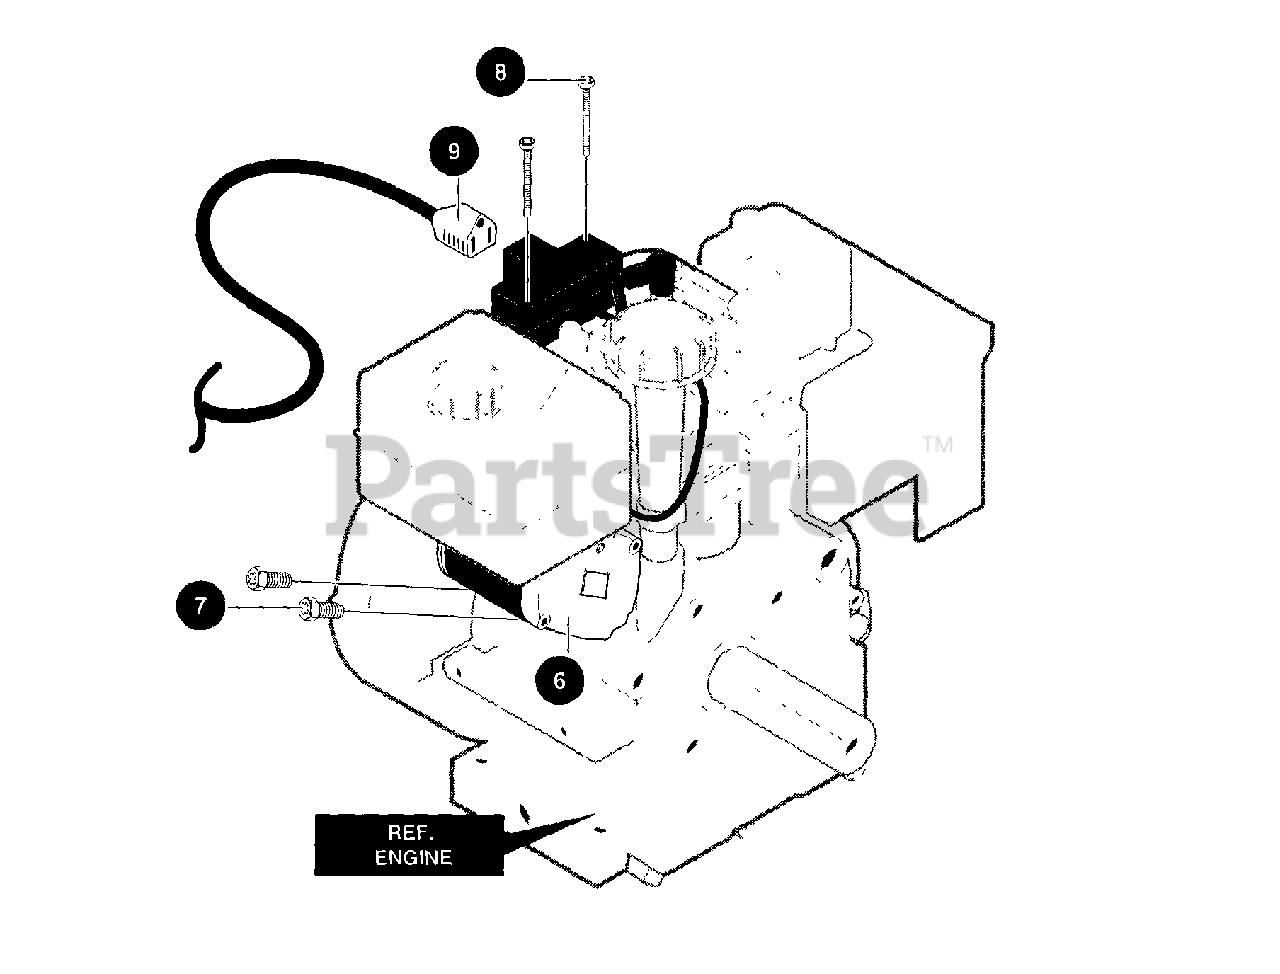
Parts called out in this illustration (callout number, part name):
6	MOTOR, STARTER
7	SCREW, 1/4-20X .50
8	SCREW, #6-32X2.50
9	CORD, STARTER
10	OWNER'S MANUAL
